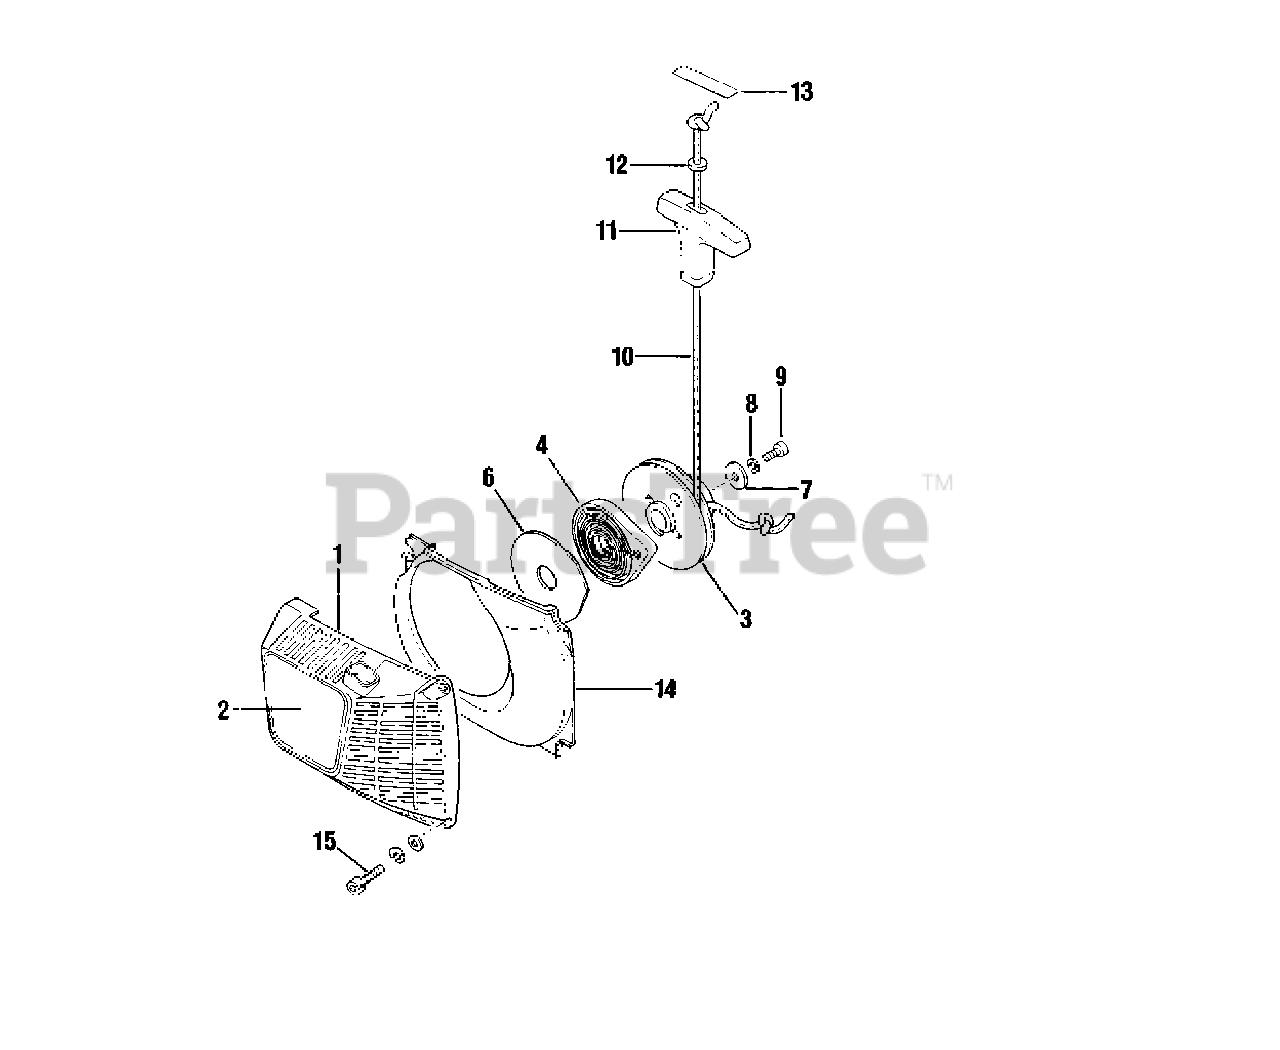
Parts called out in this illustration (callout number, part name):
1	CASE, STARTER
2	NAME PLATE
3	REEL, ROPE
4	REWIND SPRING ASSY
6	SLIDE PLATE
8	LOCKWASHER - 5
9	SCREW - 5X12
10	ROPE
11	GRIP, STARTER
12	RETAINER, ROPE
13	TAPE
14	DEFLECTOR, AIR
15	SCREW - 5X20
